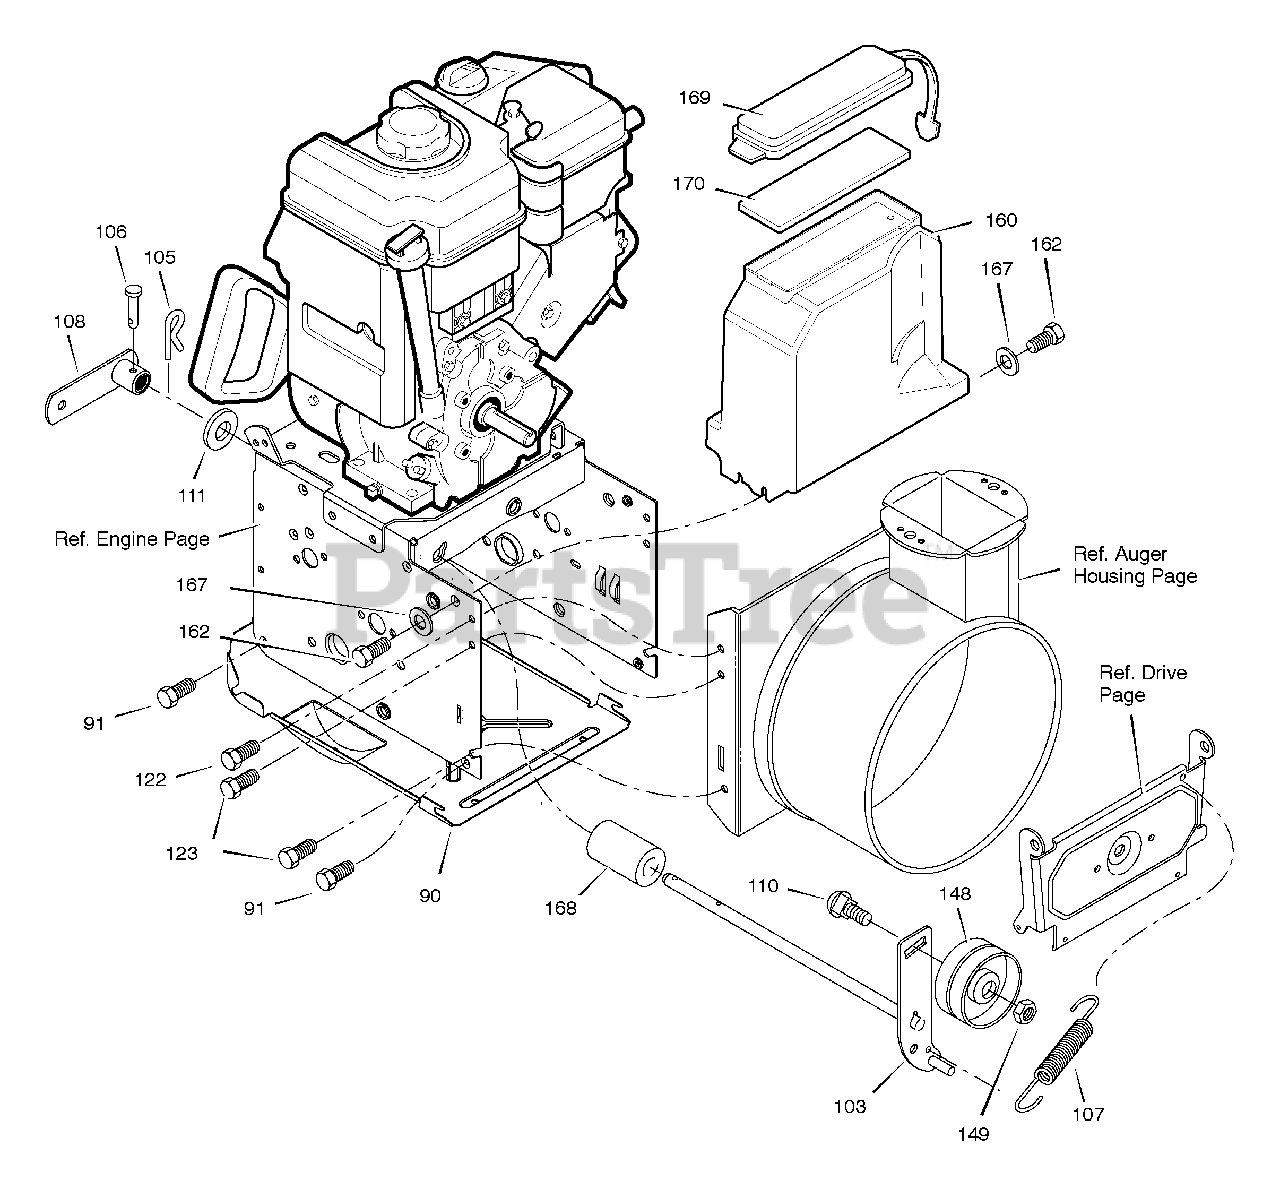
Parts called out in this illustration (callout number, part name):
90	COVER, BOTTOM
91	SCREW, 1/4-20X .63
103	IDLER ASSEMBLY, AUGER
105	PIN, HAIR .38DIAX1.64LG
106	PIN, CLEVIS 3/16" DIA
107	SPRING, TENSION
108	ASSY., SPRING ATTACH
110	BOLT, 3/8-16X1.25 CARR.
111	WASHER, FLAT
122	SCREW, TAP 5/16-18 X .50
123	SCREW, TAP 5/16-18 X .75
148	PULLEY, IDLER
149	NUT, JAM 3/8-16
160	COVER, BELT
162	SCREW, TAP
167	WASHER, FLAT
168	SPACER, AUGER BRACKET
169	LID, TOOL BOX
170	PAD, FOAM
